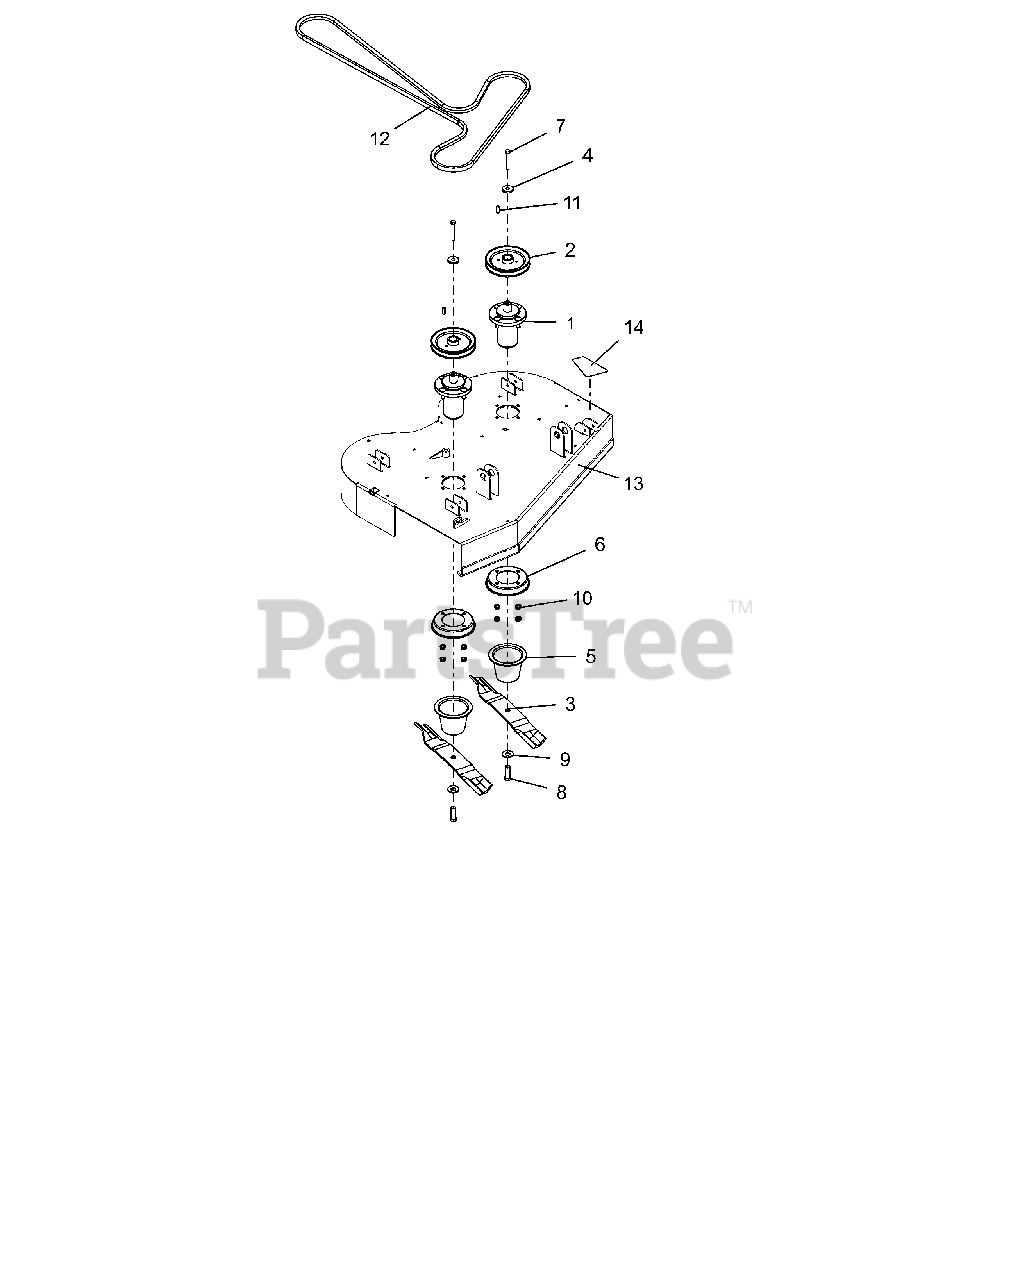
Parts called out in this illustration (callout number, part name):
1	ASM, MAINT FREE ALUM SPINDLE
2	PULLEY, V-1" ID X 6.00 OD
3	BLADE, 18.00" MOWER (HI-LIFT)
4	RETAINER, SHEAVE
5	GUARD, SPINDLE LOWER
6	GUARD, SPINDLE TOP
7	BLT, HEX .38-16X2.75 G8 ZCC
8	BLT, HEX .62-18X1.75 G8 ZCC
9	WSHR-BLVL .669X1.535X.138
10	NUT-LK-CTR-FLG .375-16 GF ZCC
11	KEY, SQ .25X.25X1.00 RC 40-50
12	V-BELT, B RAW EDGE EPDM
13	KIT, 34" DECK W/SAFTEY DECALS
14	GRIP, STEP
